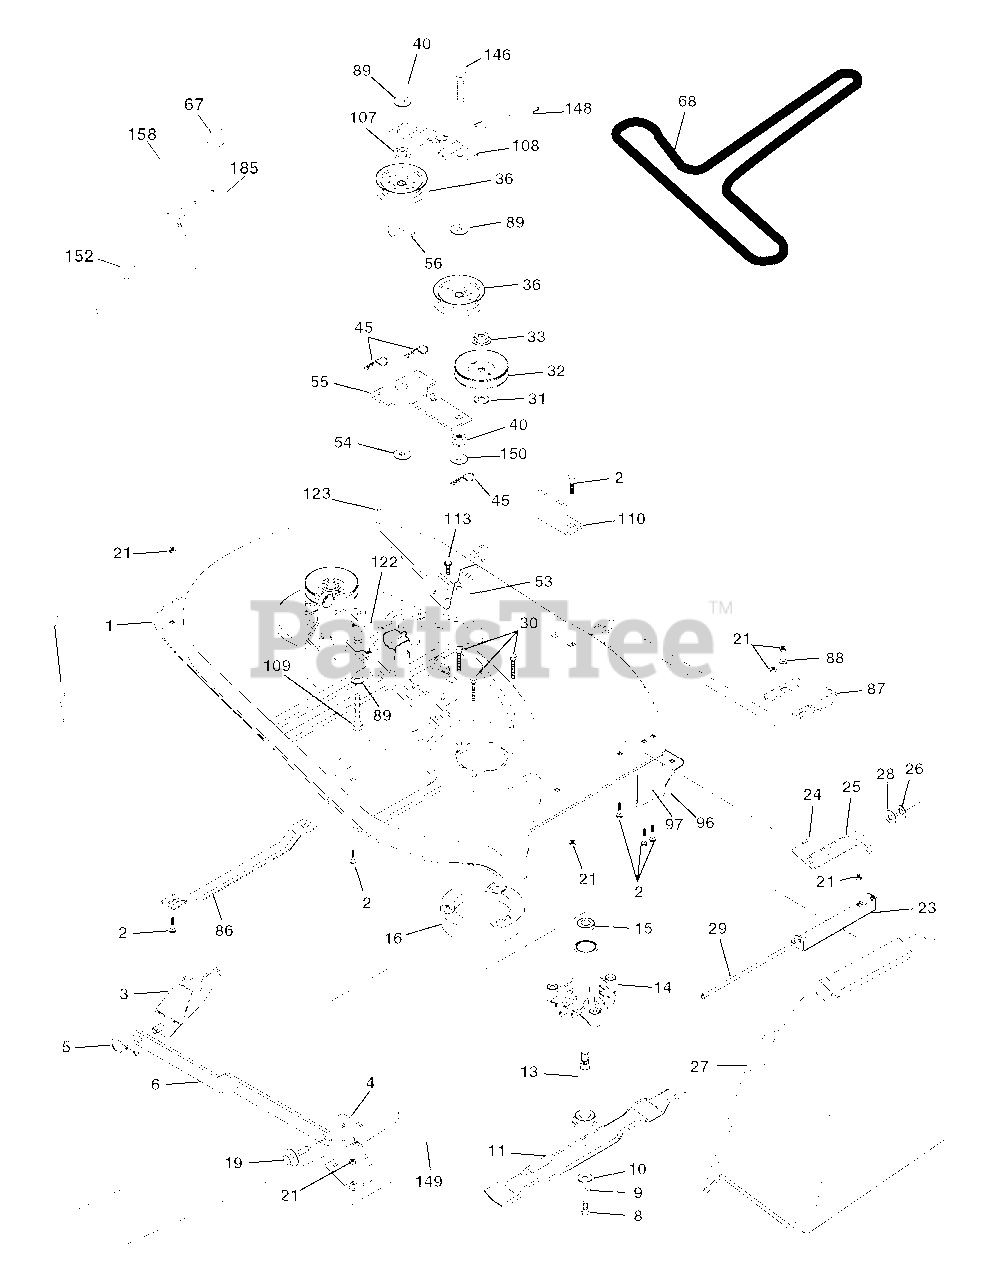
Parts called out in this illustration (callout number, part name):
1	Mower Housing Assembly
2	Bolt Carriage 5/16-18 x 3/4
3	Bracket Asm Fr. Sway Bar
4	Bracket Deck Sway Bar 38"/42"
5	Retainer Spring
6	Bar Sway Deck
8	Bolt 3/8-24 x 1.25 Gr. 8
11	Blade Mower
13	Shaft Assembly, Mandrel, Vented
14	Housing, Mandrel, Vented
15	Bearing, Ball, Mandrel
18	Blade Rdhd Sqnk 5/16-18 x 5/8
19	Bolt, Shoulder
20	Baffle Vortex Front
21	Nut
23	Bracket, Mower Deflector
24	Cap, Sleeve
25	Spring, Torsion, Deflector
26	Nut, Push
27	Shield, Deflector
29	Rod, Hinge
30	Screw Thdrol.
31	Washer, Spacer
32	Pulley, Mandrel
33	Nut, Toplock
36	Pulley, Idler, Flat
37	Pulley, Idler Flat
40	Nut, Crownlock 3/8-16 unc
45	Retainer
53	Brake Assembly
55	Idler Arm Assembly
56	Spacer, Retainer
67	Knob
68	V-Belt
72	Spring Brake Return
89	Washer 13/32 x 13/16 x 11 Ga.
107	Spacer Retainer
108	Stiffener, Idler Arm
122	Rod, Brake LH
123	Rod, Brake RH
144	Keeper Belt Idler Tension
148	Spring Return Idler
149	Retainer Spring Yellow
150	Washer 9/32 x 3/4 x 10 Ga.
152	Clutch Cable 38"
158	Screw Hex Thd Cut 1/4-20 x 1/2
185	Head Asm Cable Clutch
186	Screw Hex Wsh Thdrol 3/8-16 x 2-3/4
187	Keeper Belt M Shape
188	Bolt Carriage Idler
189	Brake Stand
190	Brake Arm
191	Brake Spacer
192	Brake Assembly
193	Keeper Belt Rh Mandrel
194	Brake Guard
195	Washer 13/32 x 2 x 10 Ga.
